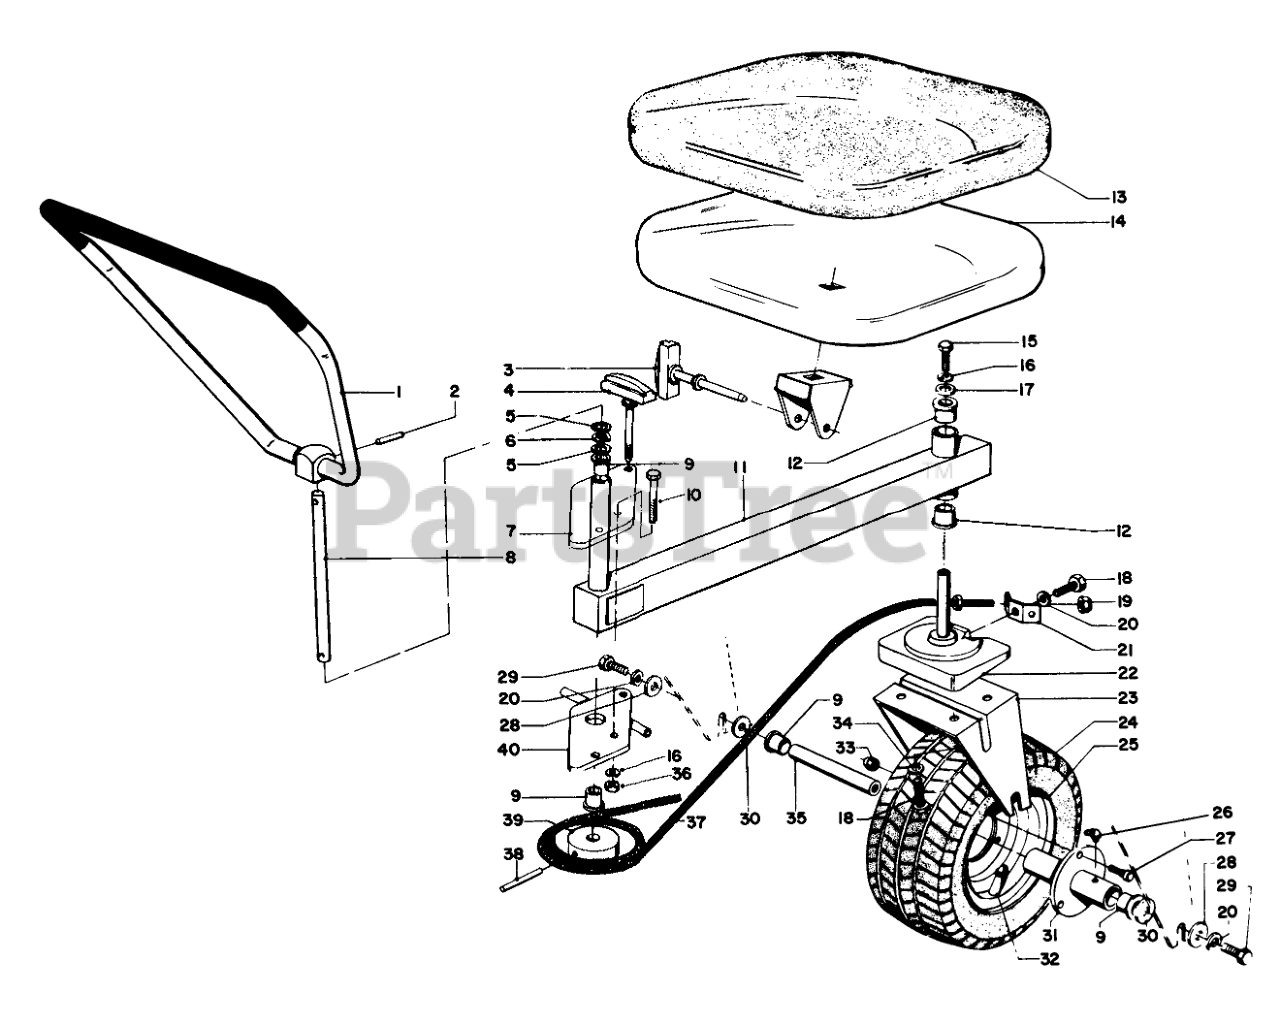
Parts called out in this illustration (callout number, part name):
1	STEERING HANDLE ASM
2	PIN-ROLL, SLOTTED
3	Handle Assembly
4	STUD & HANDLE ASM
5	WASHER-THRUST
6	3/4 SPRING WASHER
7	Plate, Upper Hinge
8	STEERING SHAFT
9	3/4IDX1LG FLANGE BSHG
10	SCREW-HH
11	Rear Frame (Incl. Ref. #9 & 12)
12	FLANGE BUSHING
13	SEAT PAD
14	Seat Assembly
15	SCREW-HH
16	WASHER-LOCK
17	WASHER
18	SCREW-HH
19	NUT-LOCK
20	WASHER-LOCK
21	CABLE BRACKET R
22	PVT CSTR/SFT WARO
23	Wheel Fork
24	Tire
25	Wheel Disc Assy.
26	FITTING-LUBE, 45 DEG
27	DRIVE STUD
28	Washer
29	4 Screw
30	THRUST WASHER
31	Hub (Incl. Ref. #9)
32	STEM-VALVE
33	LUG NUT
34	WASHER-LOCK
35	Shaft
36	NUT-HEX
37	STRG SWAGED CABLE ASM
39	FRT STRG PULLEY RO
40	Plate, Lower Hinge
